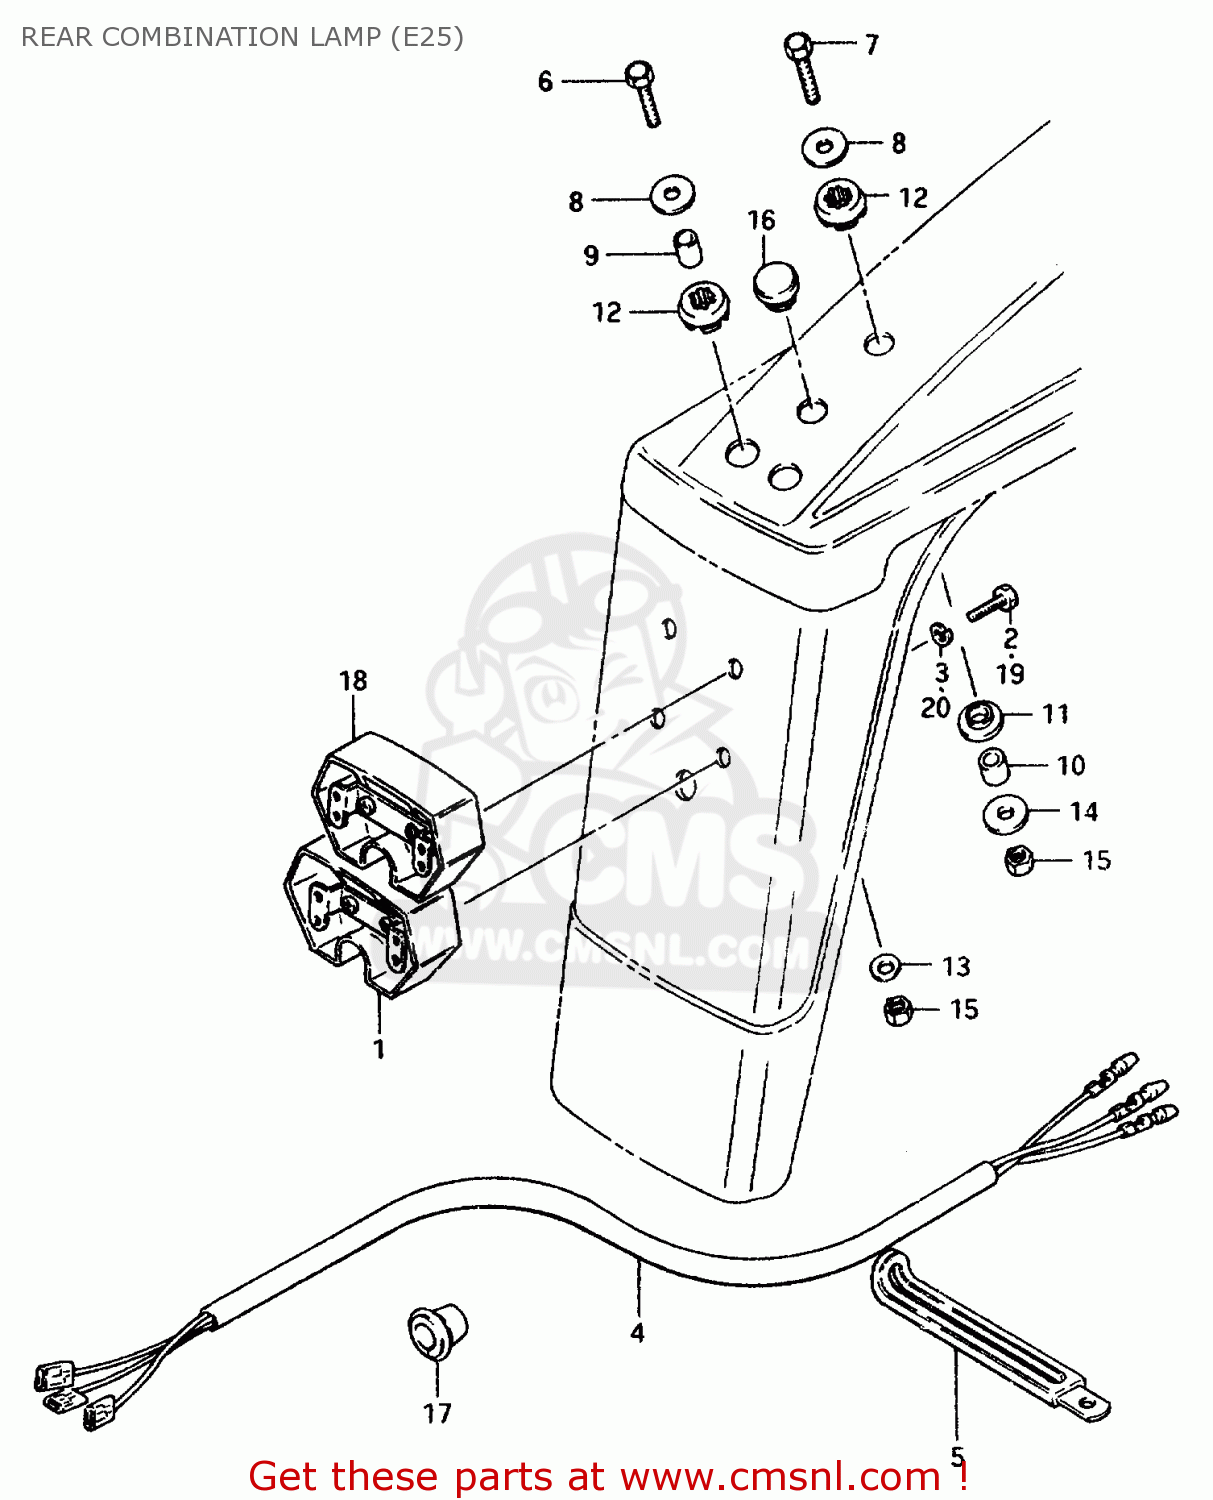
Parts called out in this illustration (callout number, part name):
1	BRACKET, REAR RR
2	BOLT, UPPER
3	LOCK WASHER
4	LEAD WIRE, TAIL LAMP
5	CLAMP L:35
6	BOLT
7	BOLT
8	WASHER (6.5X20X1.2)
9	SPACER (6.8X10X11.5)
10	SPACER
11	CUSHION
12	CUSHION
13	WASHER
14	WASHER
15	NUT
16	CAP(OD:20)
17	GROMMET
18	BRACKET, REAR RR
19	BOLT, UPPER
20	LOCK WASHER
